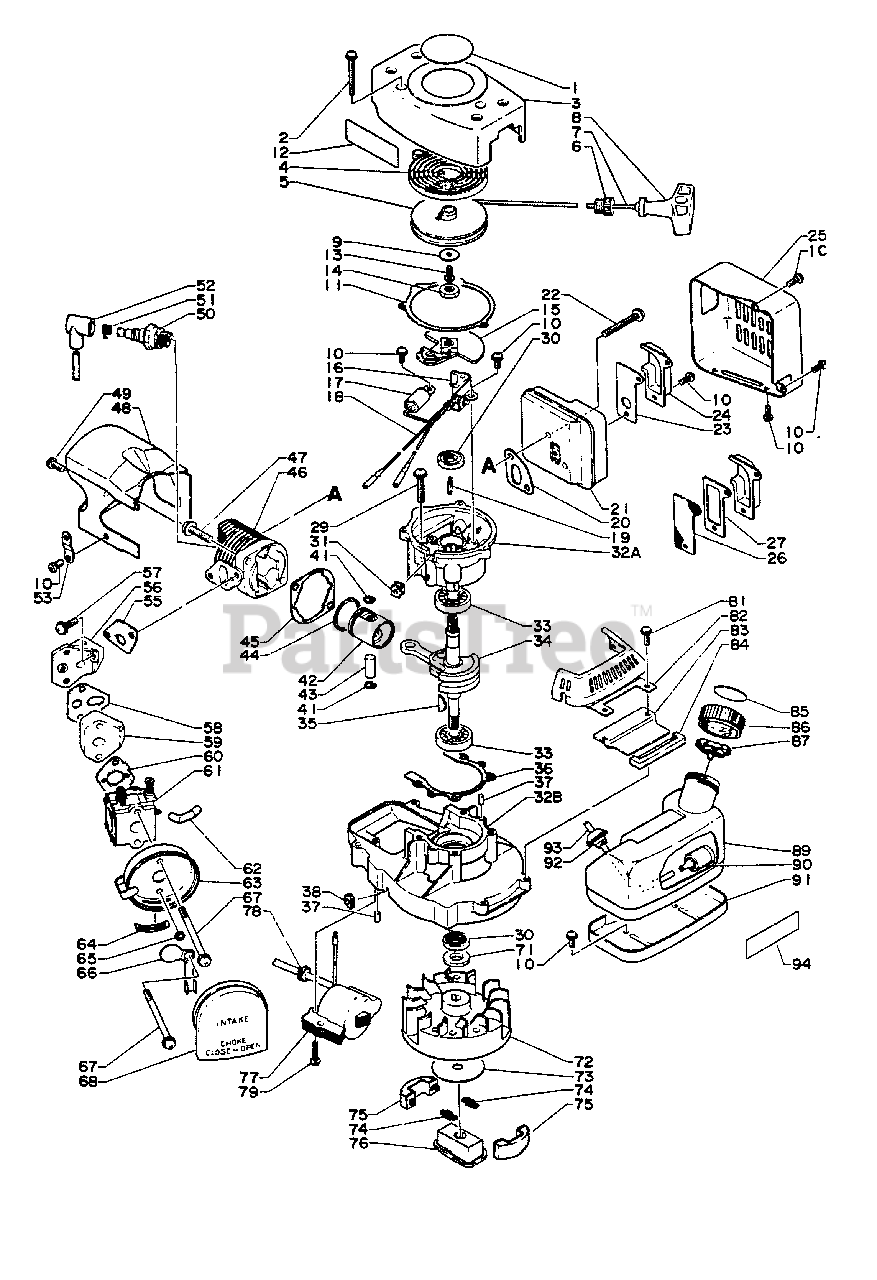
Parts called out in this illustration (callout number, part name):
1	LABEL - ECHO
2	SCREW - 4X40
3	CASE, STARTER
4	SPRING, REWIND
5	REEL, ROPE
6	GUIDE, ROPE
7	ROPE, STARTER - 3X850
8	GRIP, STARTER
10	SCREW - 4X10
11	GASKET, STARTER
12	LABEL - CAUTION
13	SCREW - 4X10
15	STARTER PAWL ASSY
16	CONTACT POINT SET
17	CONDENSER
18	LEAD - GROUND
19	PAD, OIL
20	GASKET, EXHAUST
21	CASE, MUFFLER
22	SCREW - 5X40
23	GUIDE, EXHAUST - INNER
24	GUIDE, EXHAUST
25	COVER, EXHAUST
26	SCREEN, SPARK ARRESTOR
27	RETAINER, SCREEN
29	SCREW - 5X30
30	SEAL, OIL
32	CRANKCASE KIT
33	BEARING, BALL - 6200
34	CRANKSHAFT ASSY
36	GASKET, CRANKCASE
37	PIN - LOCATING
41	RING, RETAINING
42	PISTON
43	PIN, PISTON
44	RING, PISTON
45	GASKET, CYLINDER
46	CYLINDER
47	SCREW - 6X20
48	COVER, ENGINE
49	SCREW - 5X10
50	SPARK PLUG -- BM-6A
50	SPARK PLUG -- BMR-6A
51	TERMINAL, SPARK PLUG CAP
52	CAP, SPARK PLUG
53	BRACKET
55	GASKET, INTAKE
56	BASE, INSULATOR
57	SCREW - 5X16
58	GASKET, INTAKE
59	INSULATOR, INTAKE
60	GASKET, INTAKE
61	CARBURETOR WA-89
62	PIPE
63	CASE, AIR FILTER
65	WASHER - 5
66	SHUTTER, CHOKE
67	SCREW - 5X57
68	FILTER, AIR
72	FLYWHEEL
73	PLATE, CLUTCH
74	SPRING, CLUTCH
75	SHOE, CLUTCH
76	HUB, CLUTCH
77	COIL, IGNITION
79	SCREW - 4X20
81	SCREW - 4X12
83	BRACKET, FUEL TANK
84	CUSHION
85	LABEL - FUEL MIX
86	CAP ASSY
87	VENT
89	TANK, FUEL
90	FILTER, FUEL
91	BRACKET, FUEL TANK
93	PIPE, FUEL - CORRUGATED
94	LABEL - MODEL
